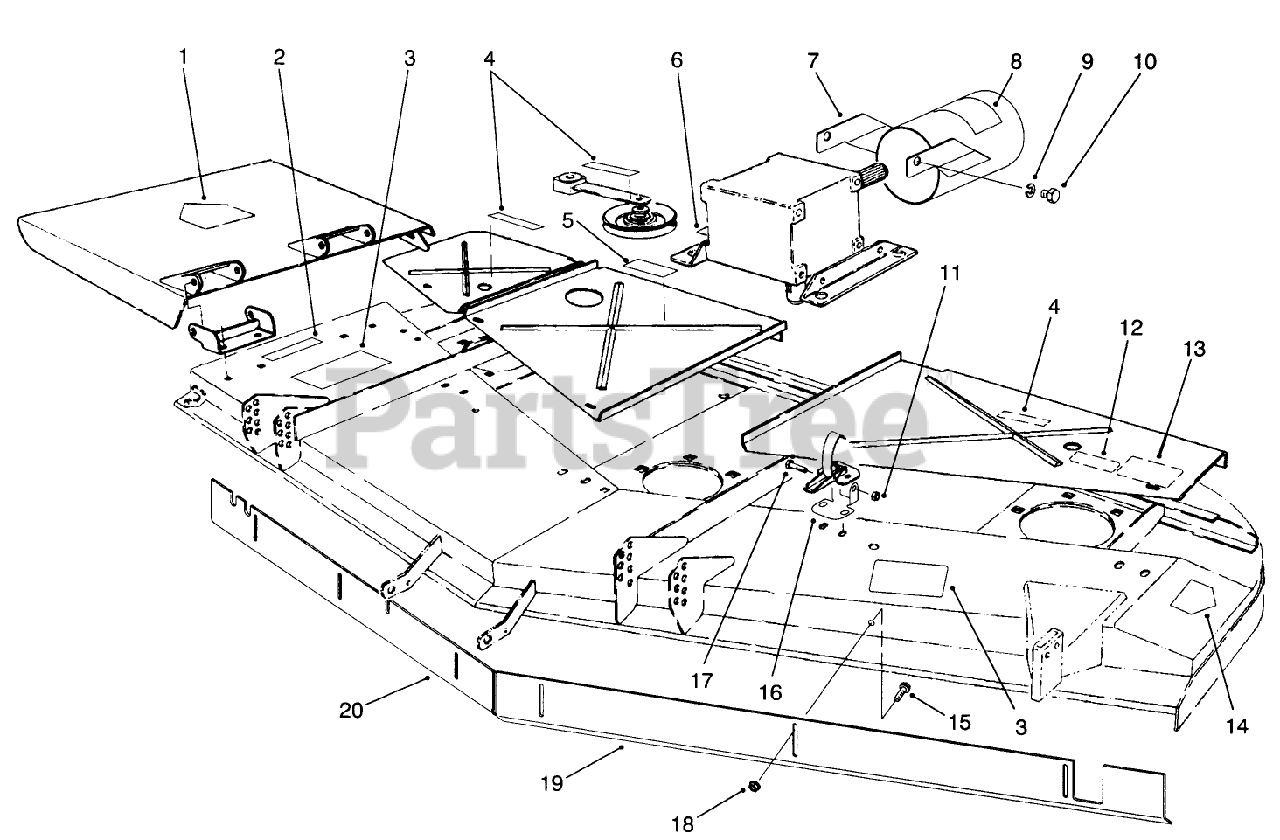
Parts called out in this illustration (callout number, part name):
1	DECAL-DANGER
2	DECAL-WARNING, DEFLECTOR
3	DECAL-DANGER
4	DECAL-DANGER
5	DECAL BLANK
6	DECAL-LUBE
7	Guard-PTO Shaft
8	DECAL-DANGER
9	WASHER-LOCK
10	SCREW-HH
11	NUT-LOCK, NI
12	DECAL-TORQUE, BLADE BOLT
13	DECAL - WARNING
14	DECAL-DANGER, INT'L
15	SCREW-HHF
16	RETAINER-LATCH
17	SCREW-HH
18	NUT-HF
19	Baffle-Front LH
20	Baffle-Front RH
